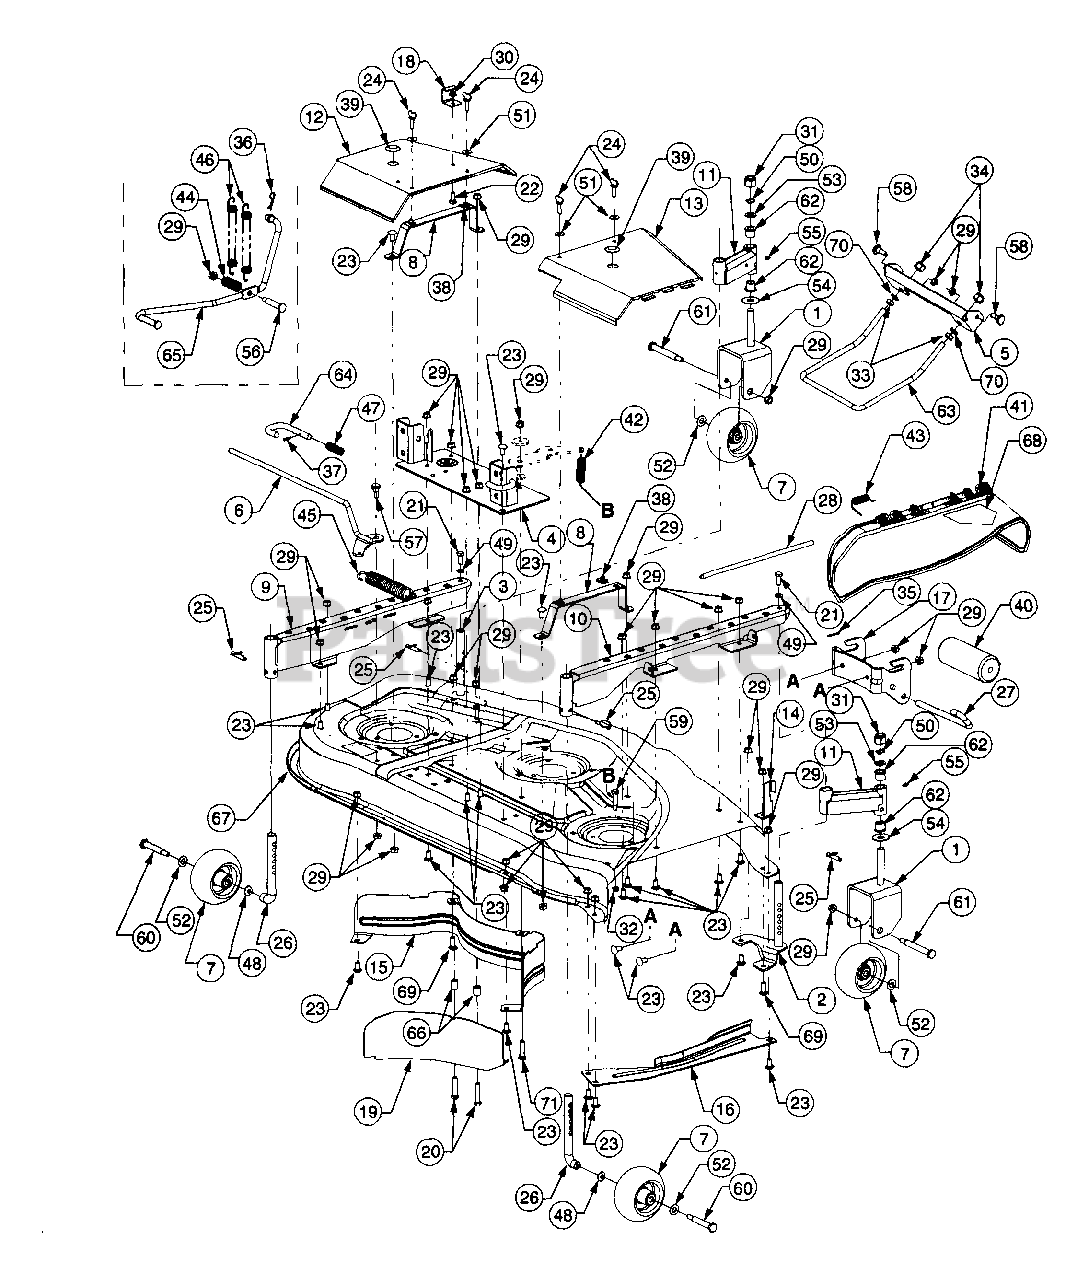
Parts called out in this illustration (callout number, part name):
1	Bracket, Castor Wheel
2	Spindle Assy, RH Front
3	Spindle Assy, LH Front
7	Wheel, Ball w/Fitting, 5 in.
9	Channel, LH Castor
10	Channel, RH Castor
11	Castor Assembly, Front
12	Guard, LH Belt
13	Guard, RH Belt
14	Stop, Chute Deflector
15	Baffle, Rear Inner
16	Guard, Finger
17	Bracket, Front Roller
18	Bracket, Handle Stop
20	Screw, Hex Cap, 3/8-16 x 1.75 GR5
21	Screw, Hex Cap, 3/8-16 x .88 GR5
22	Screw, Hex Cap, 5/16-18 x .75 GR5
23	Bolt, Carriage, 3/8-16 x .75 GR5
24	Screw, Thumb Adj, 5/16-18 x 1
25	Pin, Clevis w/Ball Detent
26	Axle, Deck Castor
27	Pin, Roller, 1/2 Dia x 7.31
28	Pin, Hinge, .375 Dia x 12.55
29	Nut, Hex Flanged Lock, 3/8-16
30	Nut, Hex Flanged Lock, 5/16-18
31	Nut, Hex Top Lock, 5/8-11 GR5
32	Nut, Hex Flange Lock, 1/4-20
33	Nut, Hex Jam, 1/2-13 GR5
34	Nut, Hex Top Nylon Lock, 1/2-13
35	Pin, Cotter, 1/8 Dia x 1
36	Pin, Int. Cotter, .092 Dia. x 1.63
37	Pin, Spirol, 3/16 x .75
38	U-Nut, 5/16-18
39	Plug, Button
41	Deflector, Chute
42	Spring, Extension, .75 OD x 6.12
43	Spring, Torsion
44	Spring, Compression, .63 ID x 2
45	Spring, Extension, 1.25 OD x 7.2
46	Spring, Extension, .91 OD x 7.33
47	Spring, Compression
48	Washer, Bell, .380 x .88 x .062
49	Washer, Lock, 3/8
50	Washer, Wave, .625 x .885 x .015
51	Washer, Bell, .340 x .872 x .060
52	Washer, Flat, .510 x 1 x .060
53	Washer, Flat, .63 x 1 x .063
54	Washer, Flat, .635 x 1.585 x .062
55	Fitting, Lube, 3/16 Drive
56	Bolt, Shoulder
57	Bolt, Shoulder, .498 Dia x .340
58	Bolt, Shoulder, .500 Dia x .434
59	Bolt, Shoulder, .374 Dia x 1.16
60	Bolt, Shoulder
61	Bolt, Step Shoulder
62	Bearing, Flange
63	Rod, Front Lift
64	Pin, Mower Support
65	Rod, LH Lift Assist
66	Spacer, .437 ID x .625 OD x .75
67	Deck Assembly w/Graphics
68	Graphic, Danger
69	Bolt, Carriage, 3/8-16 x 1.0 GR5
70	Washer, Lock, 1/2
71	Screw, Hex Cap 3/8-16 x 1.5 GR5
